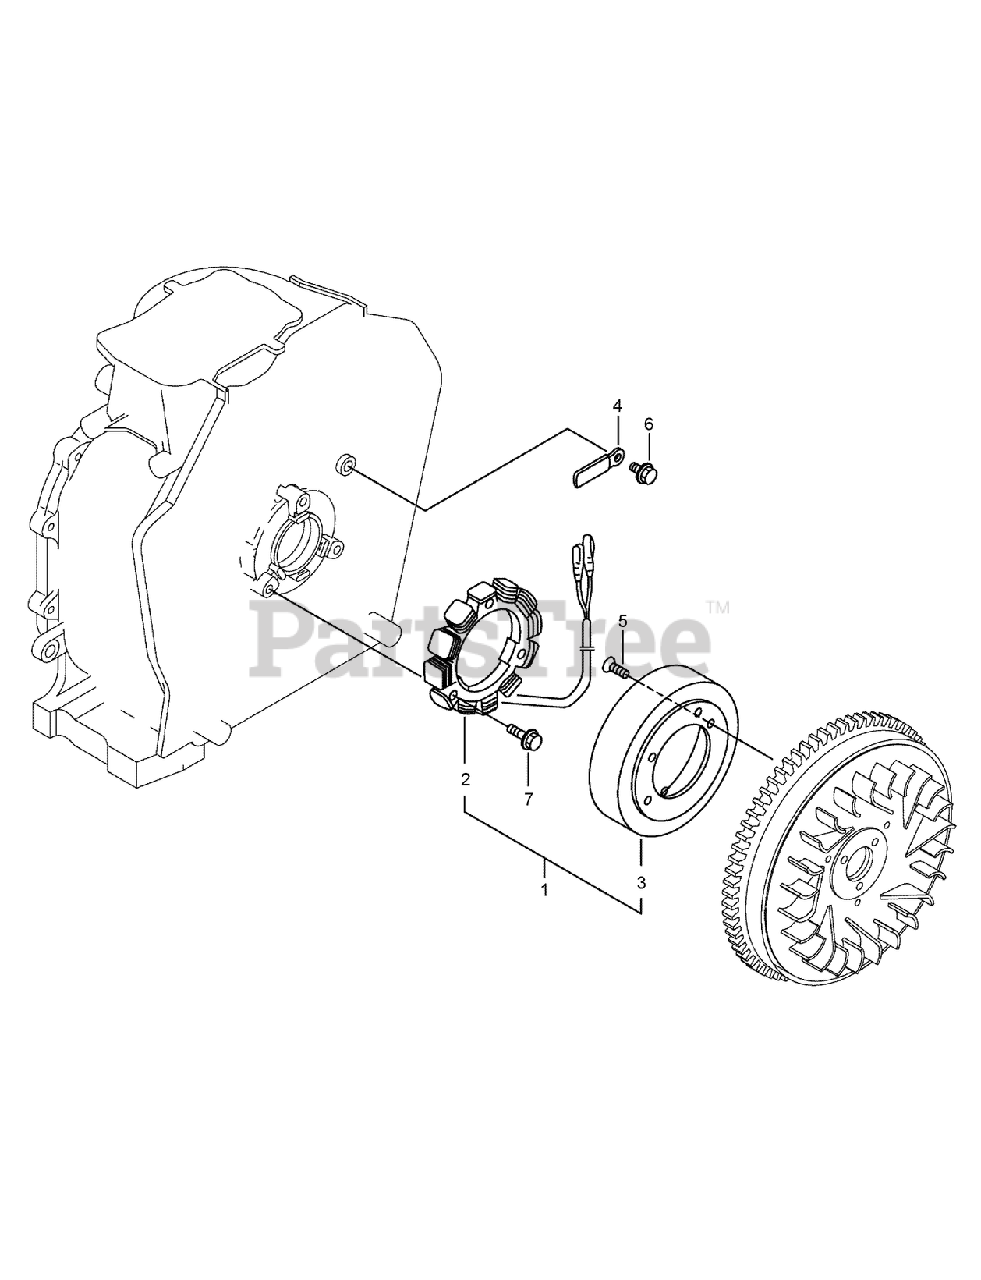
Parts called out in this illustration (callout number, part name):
1	DYNAMO ASM
2	STATOR ASM
3	WHEEL-DYNAMO
4	CLAMP-CORD
5	SCREW-CSK
